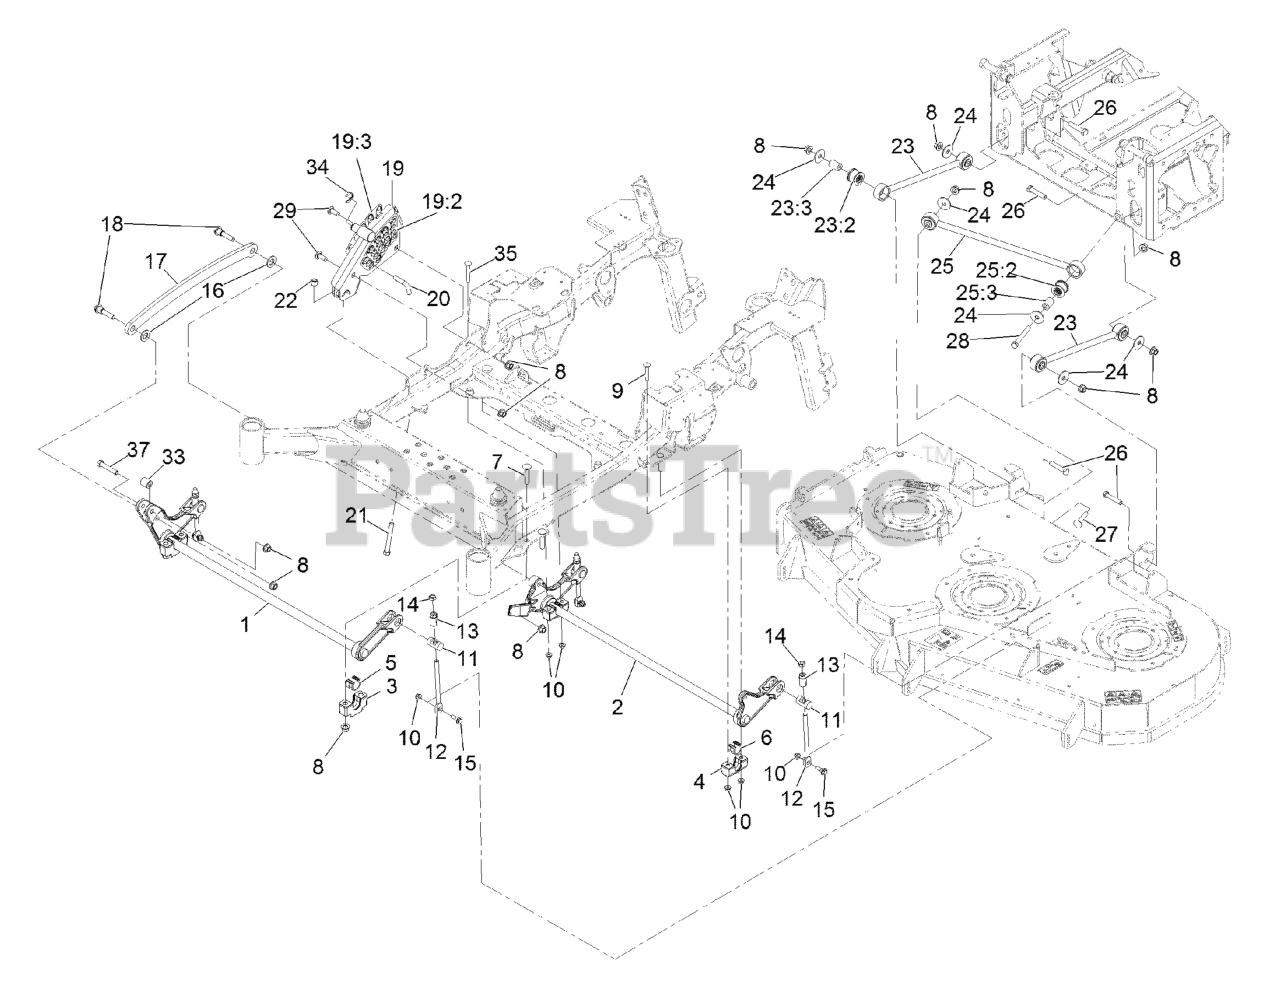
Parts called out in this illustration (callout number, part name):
1	DECKLIFT-FRONT
2	LIFT-DECK, REAR
3	SUPPORT-CROSS SHAFT, BEARING
4	SUPPORT-CROSS SHAFT, BEARING REAR
5	BEARING-CROSS SHAFT, FRON
6	BEARING-CROSS SHAFT, REAR
7	Bolt-Carriage 1/2-13 X 2 1/2 Spl Neck
8	Nut-Lock 1/2-13
9	Bolt-Carriage 3/8-16 X 2 1/4
10	NUT-HF, NI
11	TRUNNION
12	LINK-ADJUSTER, DECK LIFT
13	ADJUSTER-LIFT, DECK
14	NUT-JAM
15	SCREW-SHOULDER, HHF
16	WASHER-FLAT
17	LINK-LIFT, DECK
18	SCREW-HHF, SHOULDER
19	HOC ASM
19:2	DECAL-HEIGHT OF CUT
19:3	DECAL-HEIGHT OF CUT, OUTER
20	PIN-HOC
21	BOLT-TAP
22	NUT-LOCK, NI
23	DECK STRUT ASM
23:2	BUSHING-SUSPENSION, RUBBER
24	WASHER-THRUST
25	PANHARD ROD ASM
25:2	BUSHING-SUSPENSION, RUBBER
26	SCREW-HH
27	SCREW-CARR
28	SCREW-HH
29	SCREW-CARR, SHORT NECK
33	SPACER-PIVOT
34	RING-RETAINING
35	SCREW-CARR
37	SCREW-HH
